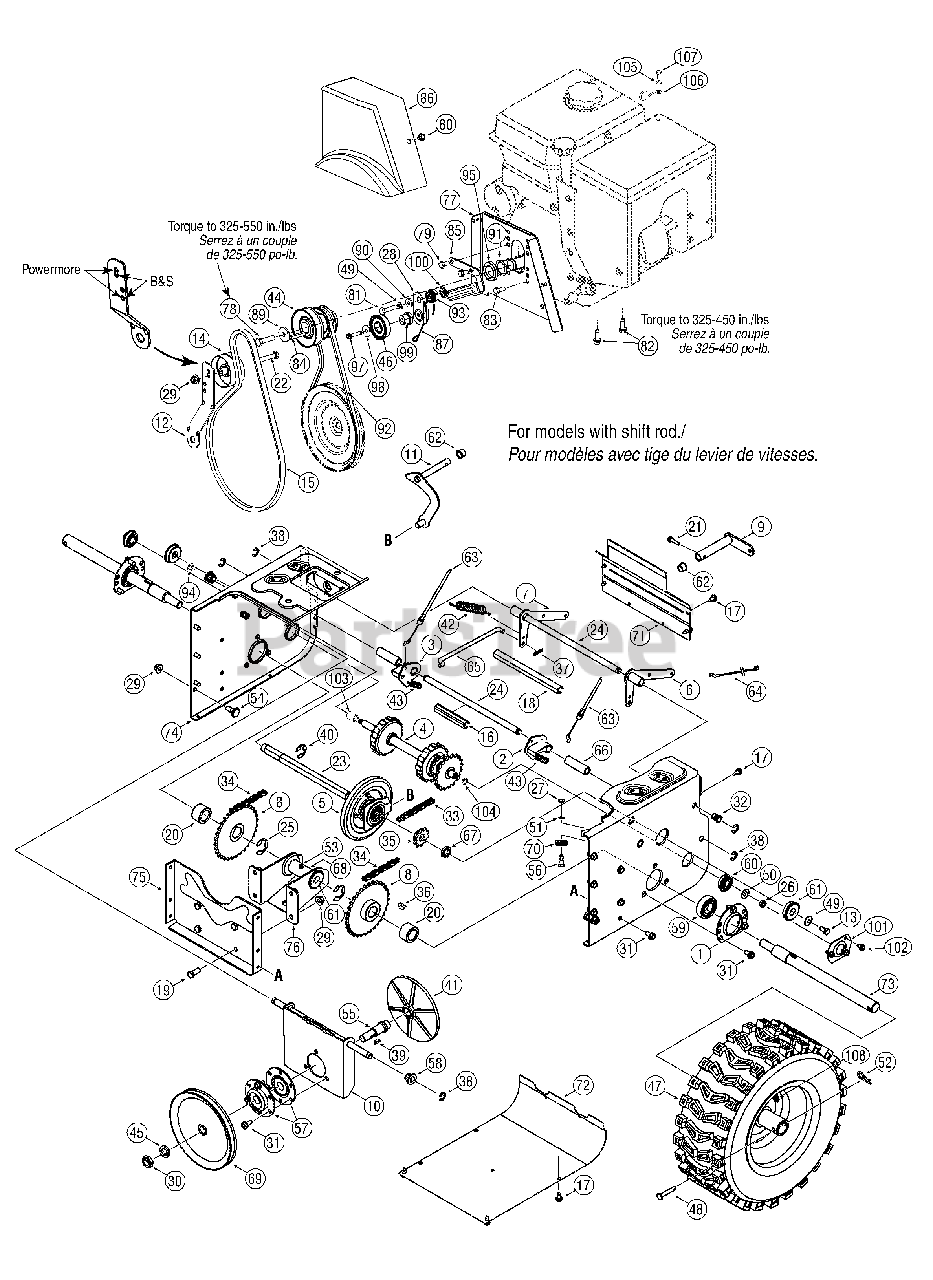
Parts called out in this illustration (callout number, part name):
1	Bearing Housing
2	LH Dog Assembly
3	RH Dog Assembly
4	Steering Shaft Assembly
5	Wheel Ass’y Bearing 6.0" OD
5	Friction Wheel Bonded
5	Hex Wash. Hd. TT Scr. 1/4-14 x .625
6	Actuator Auger Bracket Ass’y
7	Actuator Drive Bracket Ass’y
8	32T Sprocket Ass’y
9	Shift Arm Ass’y
10	Friction Drive Support
11	Shift Ass’y Rod
12	Auger Idler Bracket
13	Hex L-Bolt 5/16-18 x .62
14	Flat Idler Pulley
15	V-Belt 4L x 44.6" Lg.
16	Spacer .51 ID x 3.66" Lg.
17	Hex Wash Hd TT Scr. 1/4-20 x .625
18	Spacer .51 ID x 7.895" Lg.
19	Hex Hd. C-Sunk Scr. 3/8-16 x .880 Gr. 5
20	Spacer 1.0 ID x 1.5" Lg.
21	Hex Bolt 1/4-20 x 1.00
22	Hex Screw 3/8-16 x 1.75
23	Hex Drive Shaft
24	Actuator Shaft
25	Retaining Ring
26	Hex Nut 3/8-24
27	Hex Nut 1/4-28
28	Drive Idler Bracket
29	Flange L-Nut 3/8-16 Gr. F Nylon
30	Hex Jam Locknut 5/8-18 Gr. 5 Nylon
31	TT Screw, 5/16-18 x .75
32	Nut Insert 3/8-16 UNC
33	#41 Chain 1/2" pitch x 36 links- Endless
34	#420 Chain 1/2" pitch x 40 links-Endless
35	10T Sprocket #41 x .500
36	Woodruff Key
37	Int. Cotter Pin 5/16 DIA
38	E-ring
39	No. 61 Hi-Pro Key 3/16 x 5/8
40	Retaining Ring E-Type .875 dia.
41	Aluminum Drive Plate
42	Idler Extension Spring
43	Extension Spring .47 OD x 2.03 Lg.
44	Pulley, Dbl (w/357 cc Powermore engine)
44	Pulley, Dbl (w/420 cc Powermore engine)
45	Lockwasher 5/16 ID
46	Idler Pulley Ass'y
47	LH Wheel Ass'y Comp. 16 x 6.5 x 8 X-Trac Gray
47	RH Wheel Ass'y Comp. 16 x 6.5 x 8 X-Trac Gray
47	Tire Only
47	Rim Only Gray
47	Bearing
48	Clevis Pin
49	Cupped Washer .345 ID x .88 OD x .06
50	Flat Washer .375 ID x .812 OD x .060
51	L-Wash 1/4 ID
52	Int. Cotter Pin
53	Grease
54	Shld. Scr. .500 Dia. x .335" Lg.
55	Drive Plate Spindle
56	Hex Shld.Scr.1/4-28 x .375
57	Bearing Hsg. Ass’y.
58	Hex Flange Bearing
59	Self aligning brg. 1.0 ID
60	Ball Bearing .5625 ID x 1.3750 x .4375
61	Ball Bearing w/snap ring
62	Flange Bushing .500 ID x .627 OD
63	Steering Cable
64	Auger Idler Cable
65	Drive Clutch Rod
66	Split Spacer 1/2 x 5/8 x 2.69
67	Spacer .625 ID x 1.0 OD x .23
68	Spacer .6725ID x 1.125OD x 2.485
69	1/2" "V" Pulley .625 ID x 7.50 OD
70	Cable Guide Roller
73	Axle .995 x 12.6" Lg. (28")
73	Axle.995 x 14.10" Lg (30" & 33")
73	Axle .995 x 20.4" Lg. (45")
74	Transmission Frame Ass’y Orange
75	Frame Support Bracket
76	Axle Brg. Support Bracket
77	Belt Cover Bracket
78	Hex Screw 3/8-24 x 1.25 Gr. 8 (Powermore)
79	Hex Screw 5/16-24 x .75 Gr. 5
80	Hex Wash HD S-Tapp Scr 5/16-18 x .50
81	Hex HD. Cap Scr. 5/16-24 x 1.5 Lg. Gr. 5
82	Hex Wash HD Tap Scr 3/8-16 x 1.00
83	Shoulder Screw .50 x .145: 5/16-24
84	Square Key 1/4 x 1/4 x 1.50" Lg.
85	Belt Keeper Bracket
86	Belt Cover
87	Torsion Spring .850 x 3.33" Lg.
89	Flat Washer .406 ID x 1.25 OD x .160
90	Shoulder Spacer .3175 x .5 x .094
91	Spacer 1.155 ID x 1.5 OD x 0.150 (w/Powermore)
92	V-Belt 3/8 x 36.68" Lg. (Powermore)
93	Shoulder Spacer .340 x 1.0
94	Speed Nut .50
95	Spacer 1.004 x 1.375 x .25 (w/357 cc Powermore)
97	Hex Bolt 1/4-20 x 1.25
98	Flat Washer .265 ID x 1.0 OD x 0.030 HT
99	Shoulder Spacer
100	Push on Nut
101	Bearing Retaining Bracket
102	Hex Wash S-Tapp Scr 1/4-20 x .50
103	Spacer .566 ID x .87 OD x 1.25
104	Spacer .566 ID x .87 OD x 0,190
105	Flat Washer .330 ID x .630 OD x .0635
106	Cable Guide
107	Hex Hd. Cap Scr. MB-1.25:20 Gr. 8
108	Air Valve
